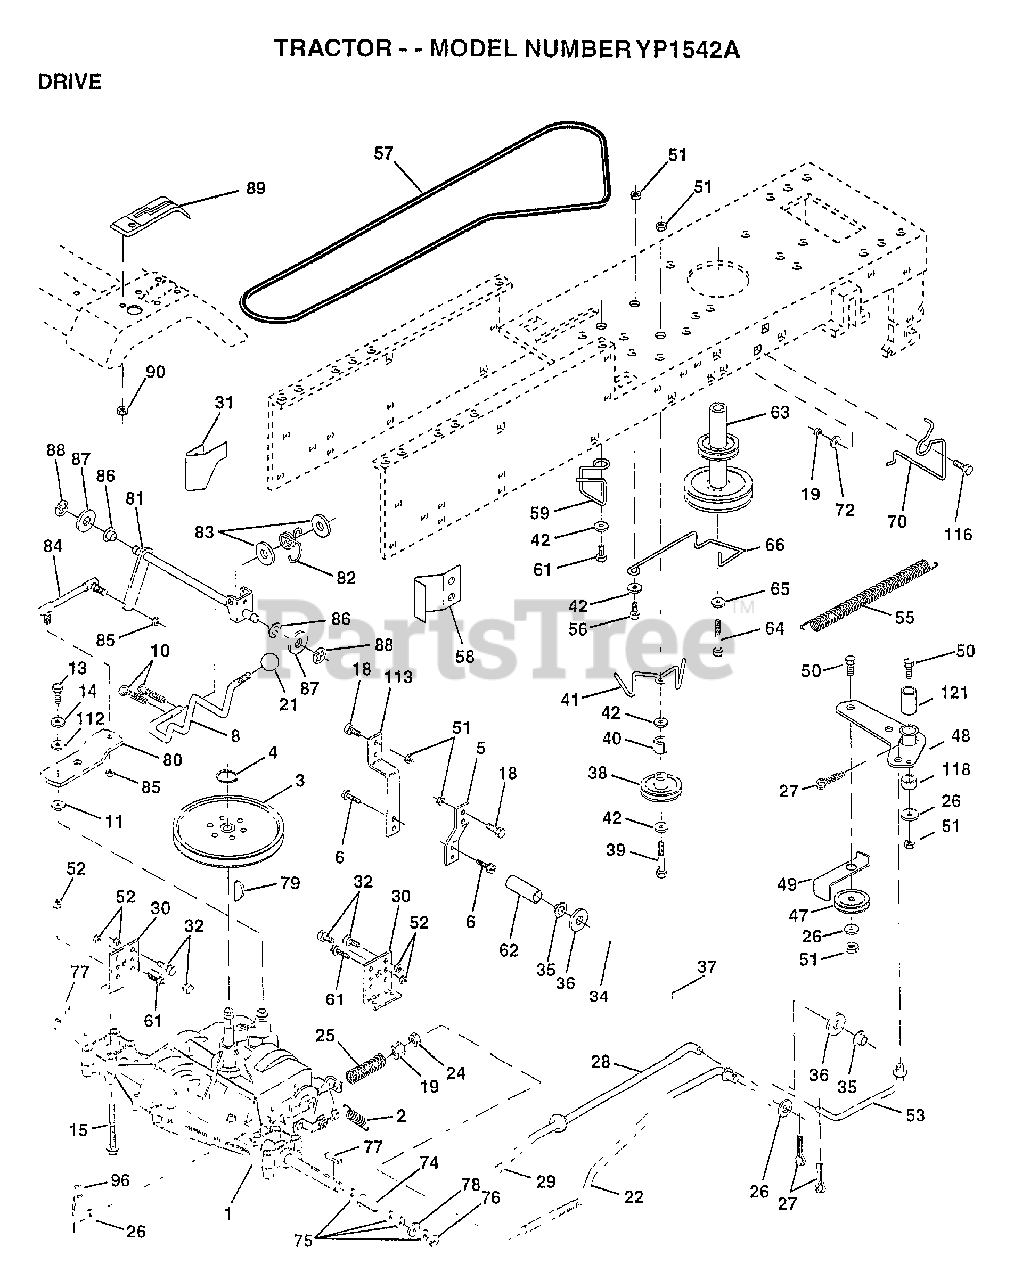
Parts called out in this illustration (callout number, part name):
1	TRANSAXLE, PEERLESS
2	SPRING.BRAKE.RETU
3	PULLEY TRANS
5	STRAP TORQUE
6	SCREW
8	ROD SHIFT FEND LT
10	PIN COTTER 1/8
11	WASH-SHFT PLT LT
13	BOLT.1/4-28.W/PAT
14	LOCKWASHER
15	BOLT.HX.FLG.5/16
18	BOLT
19	NUT
21	KNOB.DUCKHEAD.1/2
22	BRAKE ROD
24	NUT
25	SPRING ROD LT
26	WASHER
27	COTTER PIN
28	ROD.BRAKE.PARK.LT
29	PLUNGER CAP T
30	TRANSAXLE MTG BKT
31	"KEEPER,BELT LH T"
32	BOLT
34	SHAFT ASM-PEDAL F
35	NYLON BEARING
36	WASHER LT
38	PULLEY.IDLER.FLAT
39	BOLT
40	SPACER T
42	WASHER
48	BELLCRANK ASM
49	RETAIN BELT
53	"LINK, CLUTCH T"
55	"SPRING, RETURN LT"
58	"KEEPER,BELT RH T"
59	KEEPER BELT CNTSP
61	SCREW
62	PEDAL COVER T
63	PULLEY.ENGINE
64	BOLT
65	LOCKWASHER
66	KEEPER-BELT
70	KEEPER BELT ENG
72	WASHER
74	SPACER AXLE
75	WASHER
76	E-RING LT
77	SQUARE KEY
78	WASHER
80	"ROD,LINK SHIFT"
81	SHAFT.CROS.18.STR
82	"SPRING,TORSION"
83	WASHER
84	"ROD,TIE "
85	NUT.CNT.LOCK.1/4
86	BUSHING
87	WASHER D
88	KLIP RING
90	NUT
96	RETAINER M
112	WASHER LT
113	"STRAP,TORQUE"
116	BOLT RDHD 3/8-16
118	SPACER-BELLCRANK
121	NYLINER-CLUTCHING
